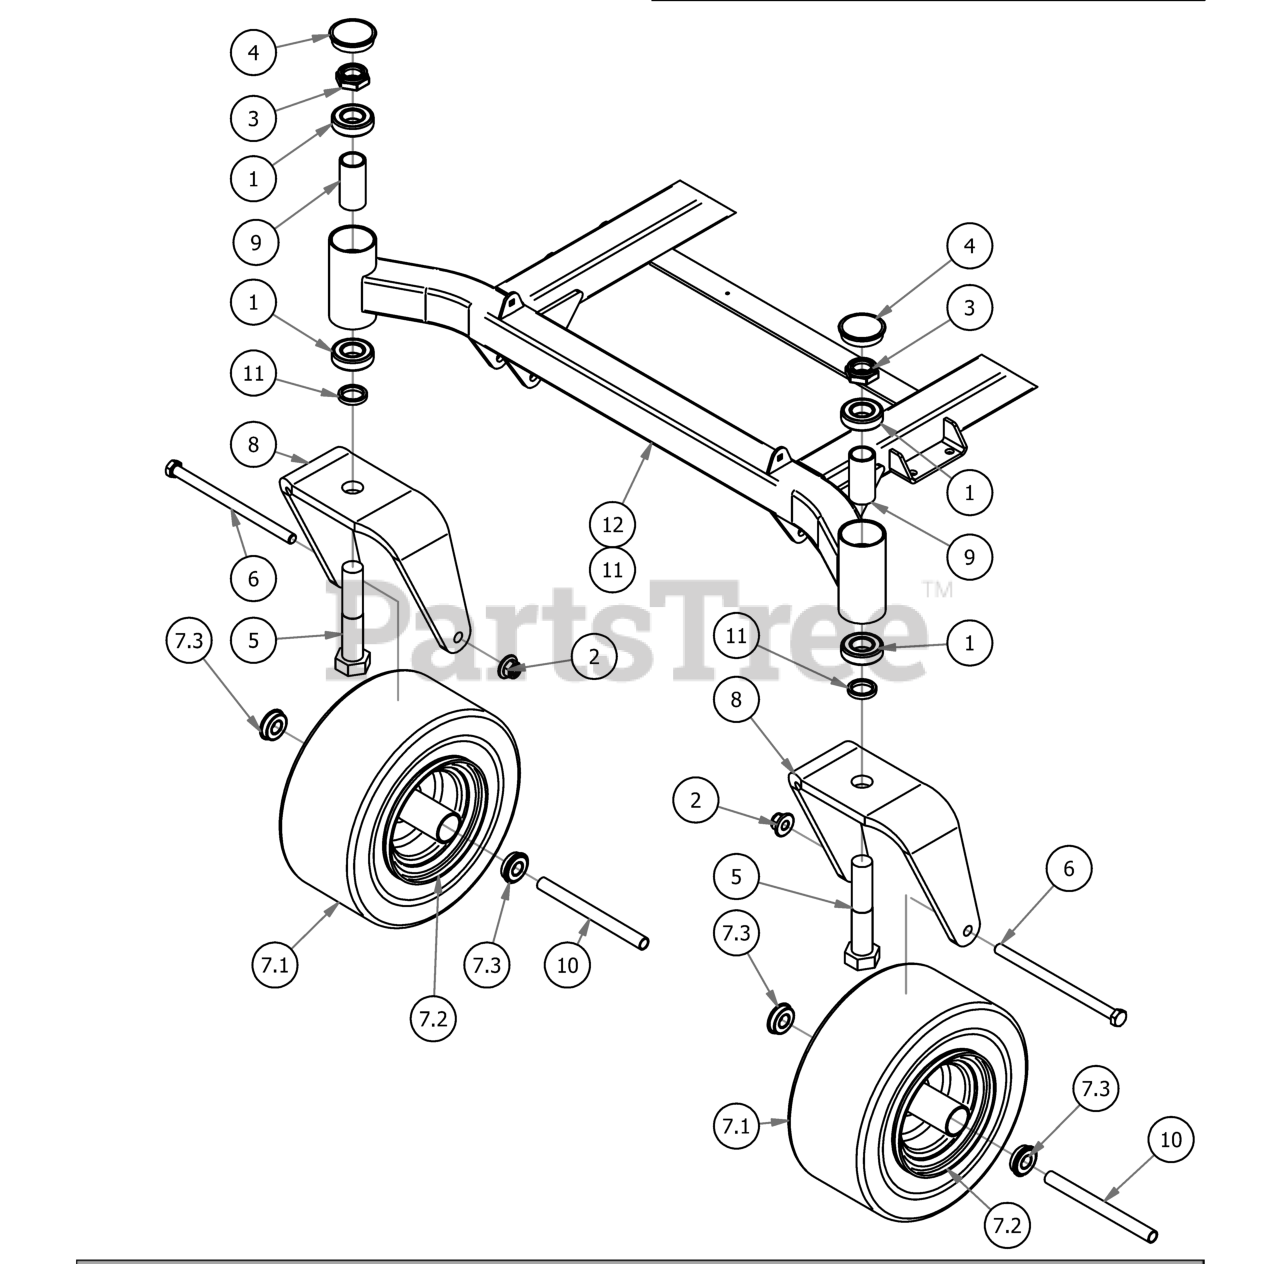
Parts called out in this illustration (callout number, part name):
1	Caster Bearing 2016 - 1641 Bearing
3	1" Fine Thread 1/2 Nylock Nut
4	2017 Bearing Cover
5	1-14 x 5 Hex Bolt Grade 8 Zinc Yellow
6	1/2" x 8 1/2 GR 5 Hex Bolt
7	Tire and Wheel Assembly
7.1	13 x 6.50 - 6 Tire
7.2	Front Tire Rim
7.3	BEARING WITH RETAINER
8	2017 ZT Front Fork
9	2016 Front Bearing Spacer
10	Front Wheel Spanner
11	Spacer, 1x1.375x.25
11	ZT 54" and 60" Frame
12	2017 MZ/ZT 42"-48" Frame
